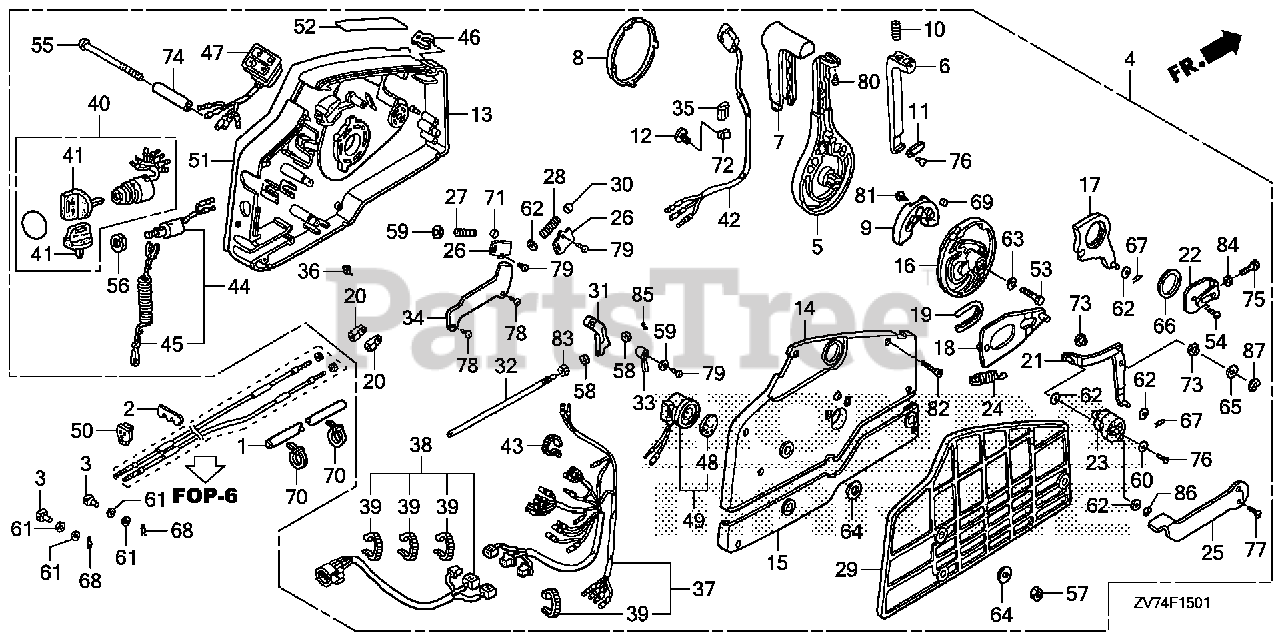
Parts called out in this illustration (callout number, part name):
1	TUBE, CORRUGATE (28MM)
2	PLATE, REMOTE CONTROL CABLE
3	PIVOT, SHIFT
4	BOX ASSY., REMOTE CONTROL (NHK MEC)
4	BOX ASSY., REMOTE CONTROL (P/T)
4	BOX ASSY., REMOTE CONTROL (P/T)(HI-LEX)
5	HANDLE, REMOTE CONTROL
6	LEVER, HANDLE LOCK
7	GRIP, REMOTE CONTROL HANDLE
8	CAP, HANDLE
9	BLOCK, NEUTRAL LOCK
10	SPRING, REMOTE CONTROL HANDLE
11	PLATE, LEVER SETTING
12	CLAMP, HARNESS
13	HOUSING, REMOTE CONTROL BOX (A)
14	HOUSING, REMOTE CONTROL BOX (B)
15	HOUSING, REMOTE CONTROL BOX (C)
16	WHEEL, CONTROL
17	ARM, SHIFT LINK
18	PLATE, SLIDING
19	COLLAR, SLIDING PLATE
20	PIVOT, SHIFT
21	ARM, LINK JOINT
22	BRACKET, LINK JOINT
23	WHEEL, ACCELERATOR
24	SPRING, ACCELERATOR WHEEL
25	LEVER, IDLE
26	PLATE, SPRING SETTING
27	SPRING, SHIFT CLICK
28	SPRING, CHOKE RETURN
29	SPACER, REMOTE CONTROL BOX
30	SPACER, CLICK SPRING
31	BLOCK, THROTTLE FRICTION
32	BOLT, FRICTION
33	SPACER, NEUTRAL SWITCH
34	CLAMP, POWER TILT CORD
35	PIPE, HARNESS GUIDE
36	SPACER, CABLE CLAMP
37	CABLE ASSY., REMOTE CONTROL (B)
38	CABLE ASSY., SWITCH PANEL
39	TIE, CABLE (2.4X92) (NATURAL)
40	SWITCH ASSY., COMBINATION
41	KEY ASSY., COMBINATION SWITCH (35100-ZV5-003 ONLY)
42	SWITCH ASSY., POWER TRIM-TILT
43	BAND (BLACK 3.5X140)
44	SWITCH ASSY., EMERGENCY STOP
45	WIRE, EMERGENCY
46	CLIP, EMERGENCY LOCK
47	LAMP ASSY., INDICATION (2-LED)
48	PLATE, TURN SIGNAL BUZZER
49	BUZZER, WARNING
50	GROMMET, CASE (LOWER) (A)
51	PLATE, REMOTE CONTROL (CAUTION PICT=SILVER)
52	MARK, FAST IDLE
53	BOLT, HEX. (8X35)
53	BOLT, FLANGE (8X35)
54	SCREW, PAN (6X10)
55	SCREW (6X95)
56	NUT, HEX. (16MM)
57	NUT, HEX. (6MM)
58	WASHER, PLAIN (4MM)
59	WASHER, PLAIN (5MM)
60	WASHER, PLAIN (5MM)
61	WASHER, PLAIN (6MM)
62	WASHER, PLAIN (6MM)
63	WASHER, PLAIN (8MM)
64	WASHER (6MM)
65	WASHER, PLAIN (8MM)
66	WASHER (28MM)
67	PIN, LOCK (6MM)
68	PIN, SPECIAL LOCK (6MM)
70	BAND, SELF-LOCK
71	ROLLER, CLICK
72	CLIP, WIRE HARNESS (6.3MM)
73	COLLAR, LINK JOINT
74	COLLAR, DISTANCE (6X10X43.5)
75	BOLT, HEX. (5X16)
76	SCREW, PAN (5X10)
77	SCREW, OVAL (5X12)
77	SCREW, FLAT (5X12)
78	SCREW, TAPPING (5X8)
79	SCREW, TAPPING (5X10)
80	SCREW, TAPPING (5X12)
81	SCREW, TAPPING (6X16)
82	SCREW, TAPPING (5X25)
83	NUT, HEX. (6MM)
84	NUT, HEX. (5MM)
85	E-RING (3MM)
86	E-RING (4MM)
87	E-RING (7MM)
